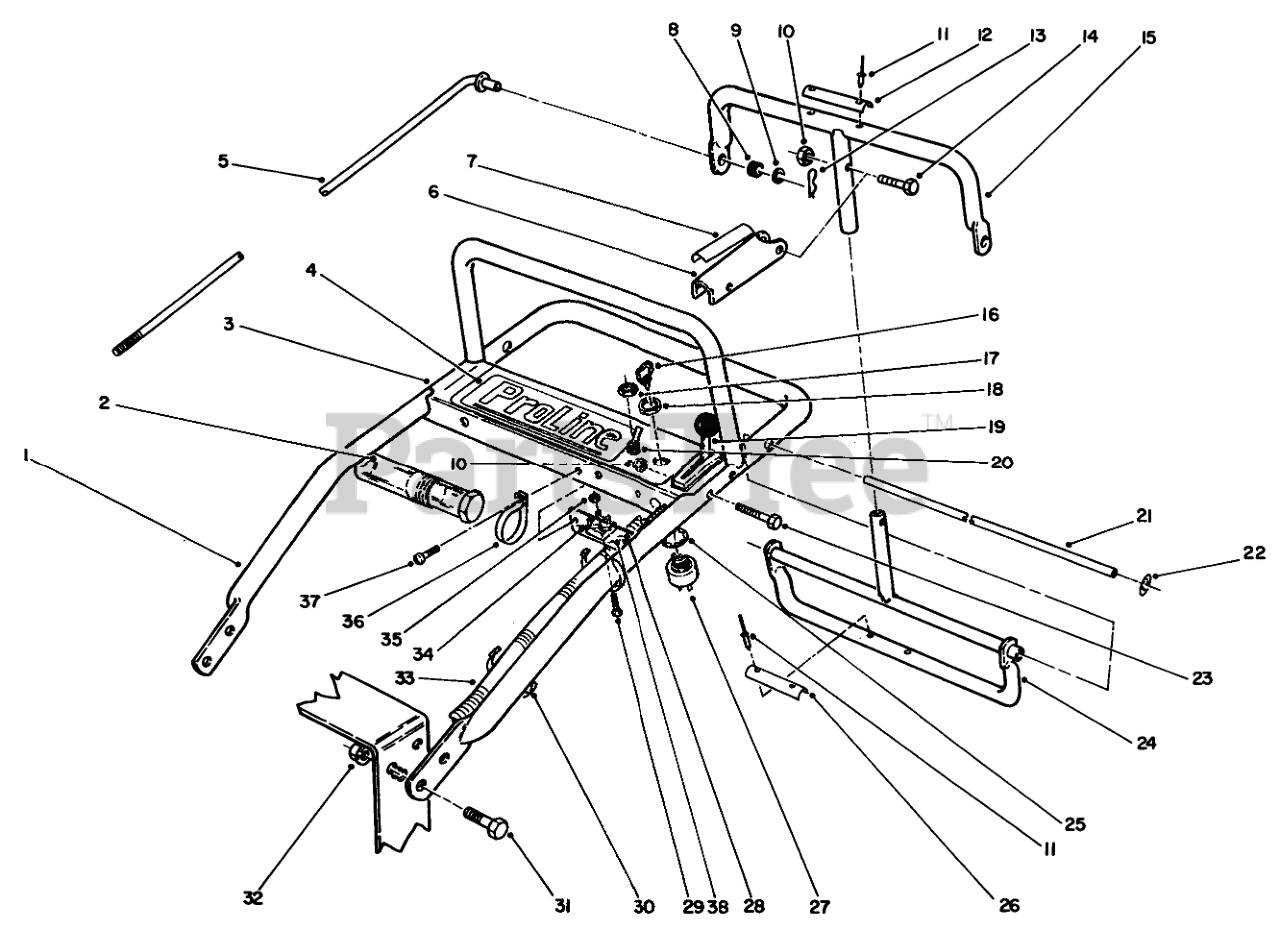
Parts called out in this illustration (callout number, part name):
1	Handle-Upper
2	TUBE-MANUAL
3	CONTROL PANEL B
4	DECAL - CONTROL PANEL
5	CONTROL ROD B
6	Lever-Parking Brake
7	DECAL-LEVER, PARKING
8	GROMMET-RUBBER
9	WASHER-FLAT
10	NUT-LOCK, NI
11	RIVET-BLIND
12	DECAL-CONTROL BAR
13	PIN-COTTER
14	SCREW-SHH
15	Bar-Control
16	KEY-IGNITION
17	NUT
18	NUT-HH
19	CONTROL-THROTTLE
20	Switch
21	PIVOT ROD
22	NUT-PUSH-ON, CIRCULAR
23	SCREW-SHH
24	Control Pivot
25	WASHER-TOOTH, INTERNAL
26	DECAL-REVERSE HANDLE
27	Switch-Ignition (Incl. Ref. #16, 18 & 25)
28	PANEL-BOTTOM
29	SCREW-HWH
30	TIE-CABLE
31	SCREW-HHF
32	NUT-HF
33	Wire Harness
34	RECTIFIER-BRIDGE
35	NUT-LOCK, NI
36	CLAMP-R
37	SCREW-HWHTF
38	RELAY
